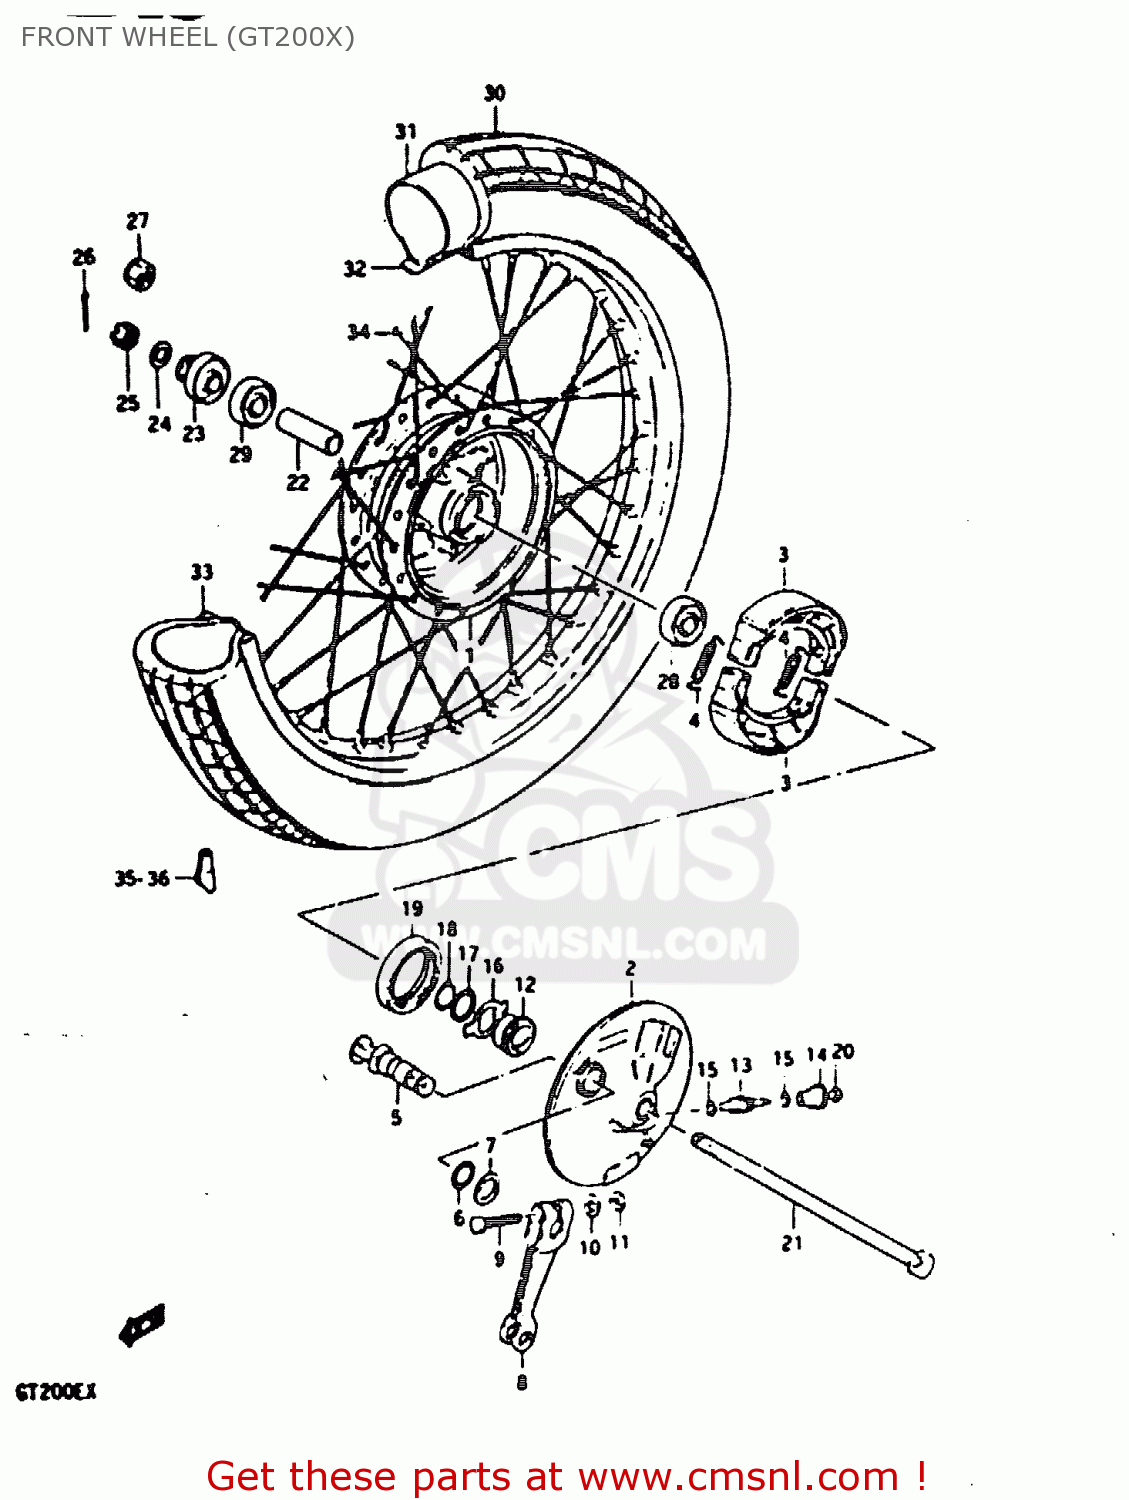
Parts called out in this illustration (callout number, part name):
1	HUB, WHEEL
2	PANEL
3	SHOE,BRAKE (MCA)
4	SPRING
5	CAM,FRONT BRAKE
6	O-RING,BOSS
7	WASHER (15X24X1.6)
8	LEVER,REAR BRAKE CAM
9	BOLT 6X40
10	WASHER
11	NUT
12	GEAR,SPEEDOMETER
13	PINION,SPEEDOMETER
14	BUSHING,SPEEDOMETER PINION
15	WASHER (5.1X9X0.4)
16	DRIVER,SPEEDOMETER GEAR
17	WASHER(22.5X27X1)
18	CIRCLIP
19	SEAL,OIL(26X38X4)
20	SEAL,OIL(6X10X3)
21	AXLE, FRONT
22	SPACER (12.6X19X52)
23	SPACER, RH
24	WASHER
25	NUT 12MM
26	COTTER PIN
28	BEARING
29	BEARING, RH
30	TIRE,FRONT
31	TUBE,INNER
32	PROTECTOR,INNER TUBE
33	RIM, WHEEL
34	SPOKE SET
35	BALANCER,WHEEL (B)
36	BALANCER,WHEEL (30G)
